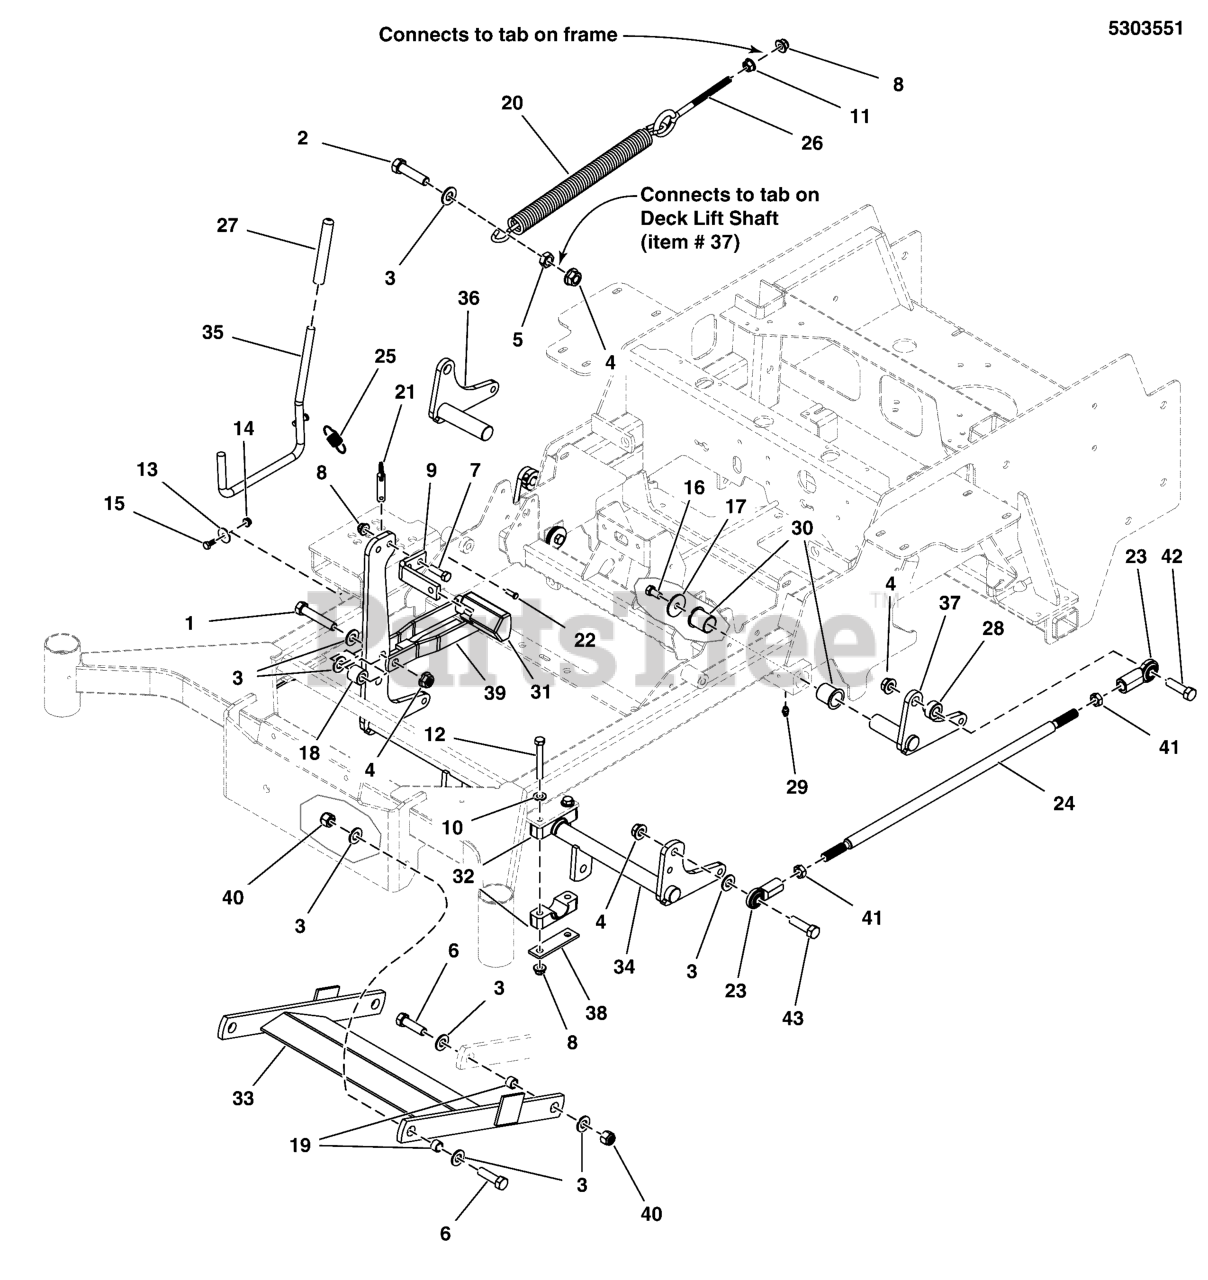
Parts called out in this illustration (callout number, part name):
1	BOLT, 1/2-13 X 2-3/4 GD5 CZ
2	BOLT, 1/2-13 X 2" GD5 CZ
3	WASHER, 1/2 SAE
4	NUT, Hex Flange, Nylock, 1/2-13
5	NUT, Hex, Jam, 1/2-13
6	BOLT, 1/2-20 X 1-3/4" GD8 CZ
7	BOLT, 3/8-16 X 1-1/4" GD5 CZ
8	NUT, 3/8 - 16 HEX NYLOCK FLANGE
9	PEDAL, FOOT - BLK
10	WASHER, 3/8 SAE
11	NUT, 3/8-16 Hex Large Serrated Flange
12	BOLT, 3/8-16 X 2-3/4" GD5 CZ
13	WASHER, 1/4" Fender
14	NUT, 1/4-20 Hex Nylock Flange
15	HHCS, 1/4-20 X 0.625, GR5, ZINC/CLEAR
16	BOLT, 3/8-16 X 3/4, PLT W/PATCH
17	WASHER, .390 X 1.50 X .109, YZ
18	SPACER, .52 X 1.00 X .88, PM, CZ
19	INSERT, Bearing
20	SPRING-EXT, 1.00 ODX13.25LGX.177WR, BLK
21	PIN, HITCH, 1/2 X 2.00 OAL, YP
22	PIN, CLEVIS, 1/4 X 1/2, PLATED
23	JOINT-BALL .500-20 THD .500ID, CLR ZINC
24	ROD, DECK LIFT, 1/2-20 X 20.00, CZ
25	SPRING-EXT, .740 ODX2.025LGX.072WR, BLK
26	EYE BOLT, 3/8-16 X 8, 3THRD, 1EYE, CZ
27	GRIP, FOAM, .475 X 4.35 X .095
28	SPACER, .52 X 1.00 X .44, CZ
29	GREASE FITTING, 1/4-28 Straight
30	BUSHING, 1.00 X 1.13 X 1.38, Plastic
31	PEDAL, Rubber
32	PIVOT BLOCK, PLASTIC
33	WELD, Deck Stabilizer - Blk
34	WELD, DECK LIFT SHAFT, 150XT - RED
35	WELD, Rod, Deck Lift - BLK
36	WELD, DECK LIFT LEVER, RH - BLK
37	WELD, DECK LIFT LEVER, LH - BLK
38	PLATE, PIVOT BLOCK SUPPORT - BLK
40	NUT, Hex, Nylon Lock, 1/2-20
41	NUT, 1/2-20 Hex Jam
42	BOLT, 1/2-13 X 2-1/4" GD5 CZ
43	BOLT, 1/2-13 X 1-3/4 GD5 CZ
